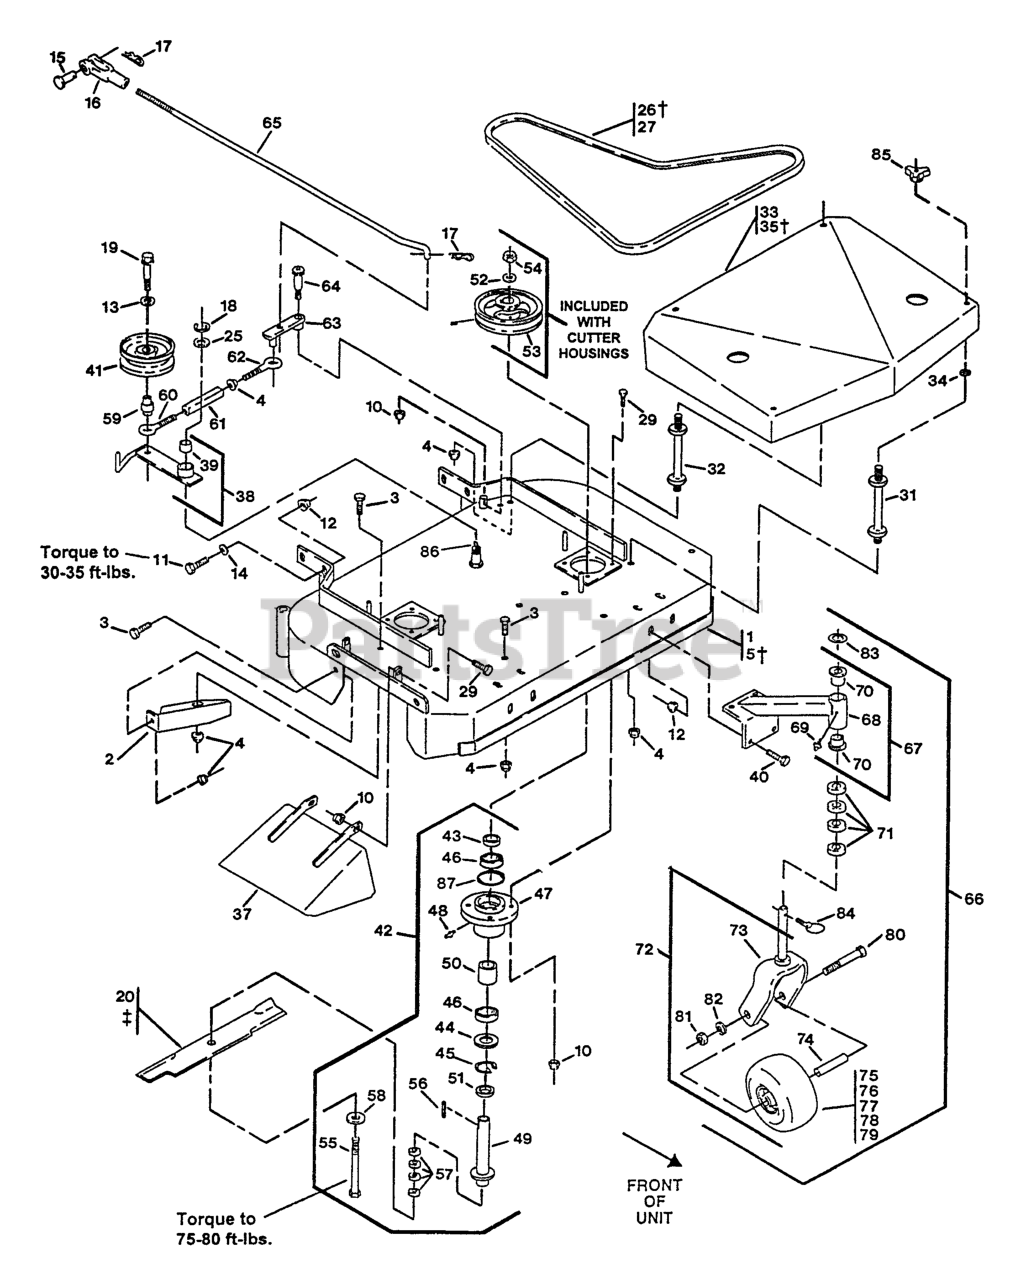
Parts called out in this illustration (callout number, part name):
2	BAFFLE-DOGLEG
15	PIN-CLEVIS
16	YOKE-ADJUSTABLE
17	PIN-COTTER
25	WASHER-SPINDLE
26	BELT,BLADE DRIVE
27	BELT,BLADE DRIVE
28	SCREW-SET
31	STUD-SHIELD, BELT (SHORT)
32	STUD-SHIELD, BELT (LONG)
35	ASM,SHIELD BELT
37	Chute
39	BEARING,POWDERED METAL
42	ASM,HOUSING CUTTER
44	SEAL,DUST
45	RING,SNAP WLDS N5000-244
46	BEARING,HD SPINDLE
47	HOUSING,CUTTER
50	SPACER,BRG/BRG
51	SPACER,BEARING &SPINDLE
52	WASHER-RETAINER, SHEAVE
55	SCREW-CAP, HH
58	WASHER-SPRING
59	BUSHING-ENGAGEMENT
60	EYEBOLT-THREAD, LH
61	BODY-TURNBUCKLE
62	EYEBOLT-THREAD, RH
64	BOLT,SHLDR KSKH
65	ARM-ASSIST, LINKAGE
66	CASTER/MOUNT ASM
67	SUPPORT ASM
70	BEARING-FLANGED
71	SPACER-CASTER
78	BEARING
79	BUSHING
83	WASHER-FLAT
85	KNOB-3 PRONG
